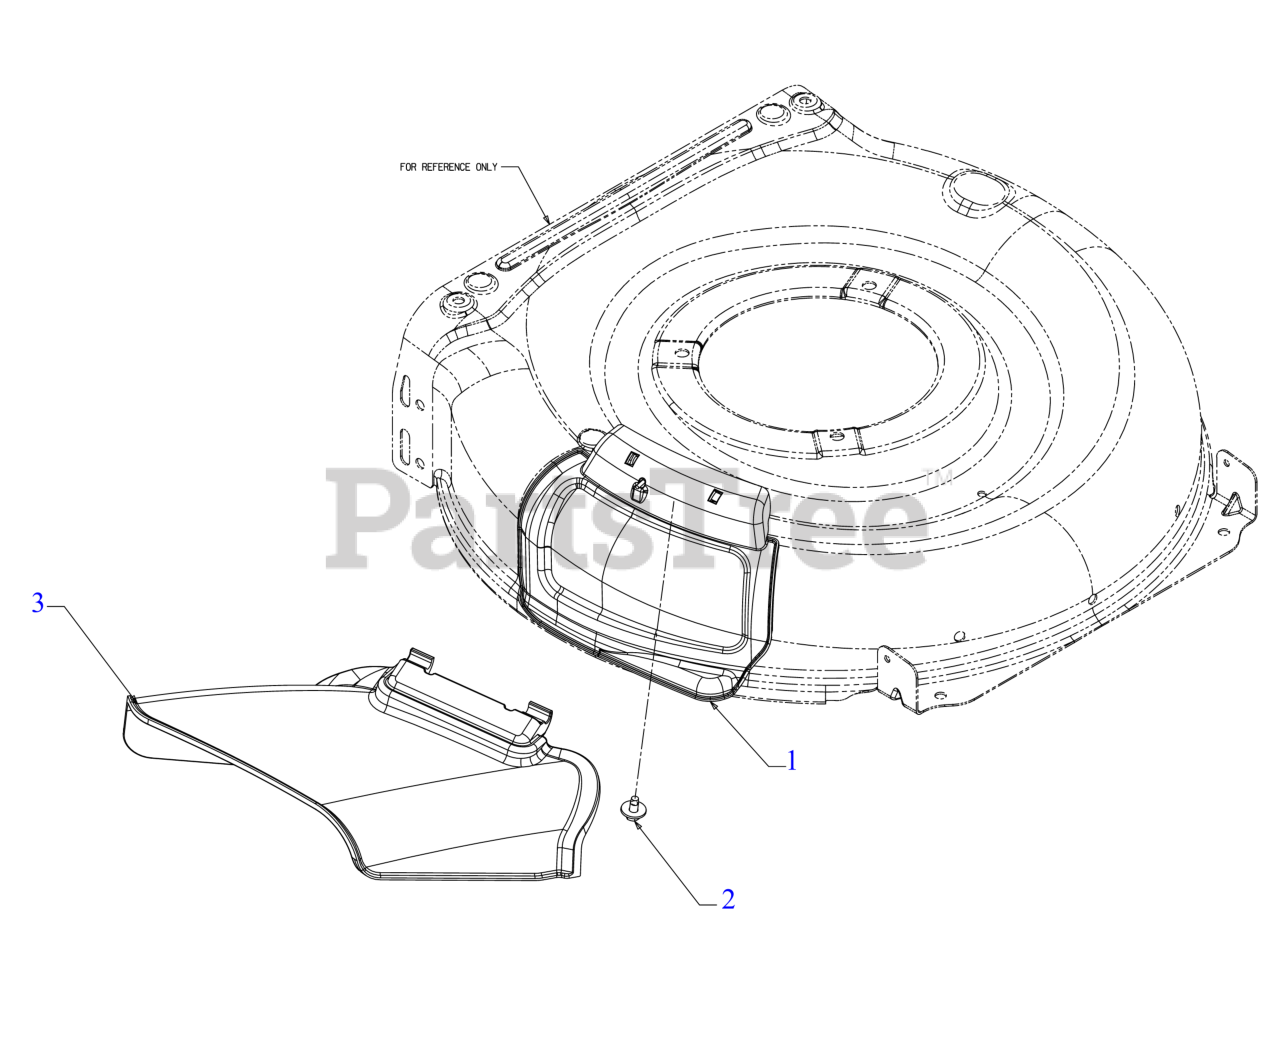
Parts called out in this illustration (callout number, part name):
1	MULCH PLUG
2	SCREW 1/4-20 x .50
3	SIDE DISCHARGE CHUTE
